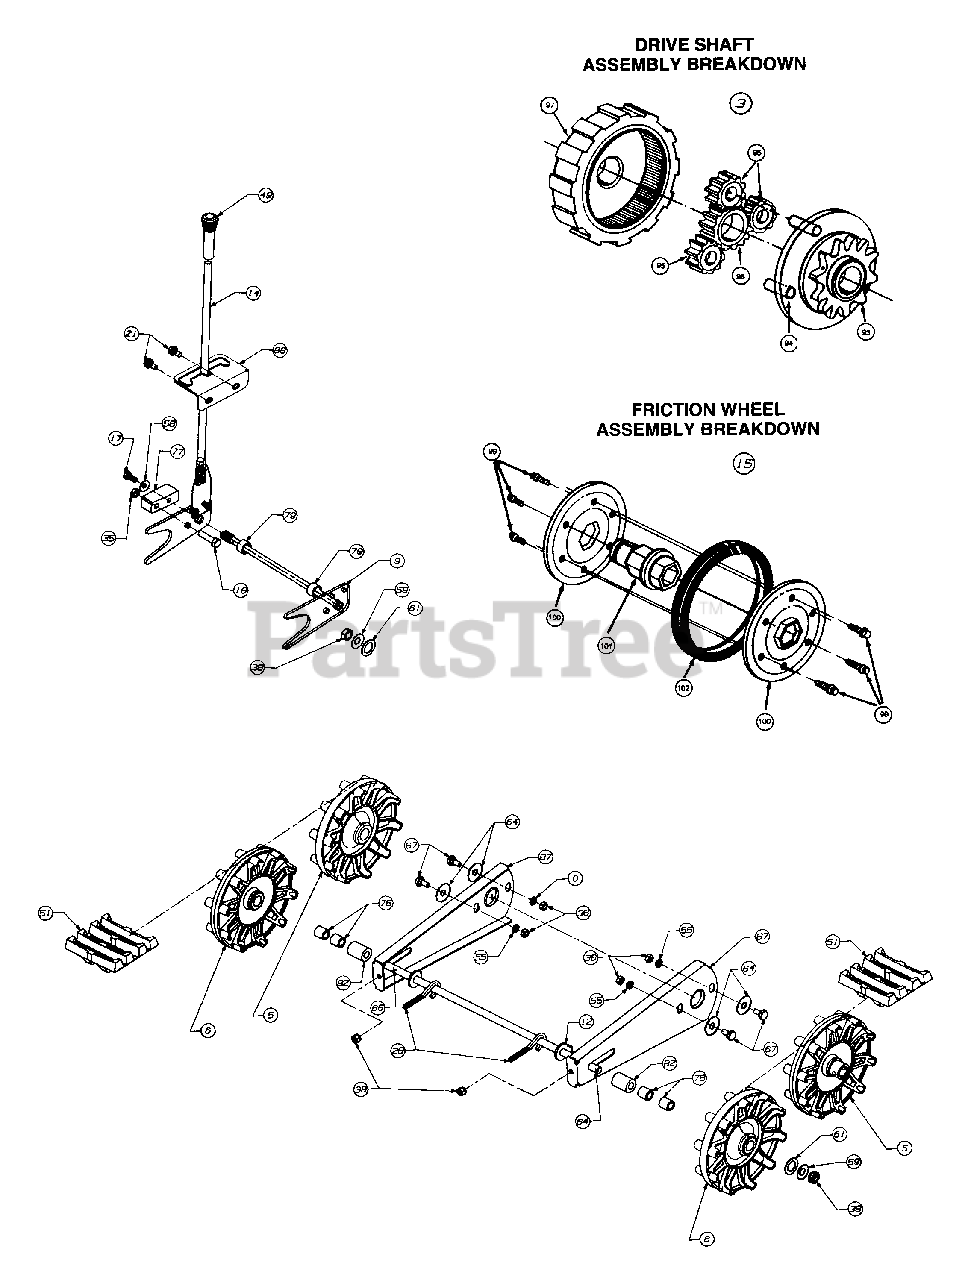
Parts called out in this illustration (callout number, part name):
3	Drive Shaft Assembly
5	Wheel Track Drive
6	Wheel Track Idler
15	Wheel Friction
17	Screw, Hex
18	Hex Screw
21	Screw, Hex
28	Bolt, Eye
35	Nut, Lock
36	Nut, Hex
38	Hex Ins. Jam
39	Hex L-Nut
51	Track
55	Washer, Lock
58	Washer, Bell
59	Washer, Bell
61	Washer, Flat
64	Washer, Flat
66	Lubricant
67	Shoulder Screw
77	Lift, Shaft Drive
78	Spacer
79	Spacer
82	Spacer
93	Carrier
94	5/16" Dowel Pin
95	12 Tooth Gear
96	18 Tooth Gear
97	Ring Gear
99	Self-Tap Screw
100	Friction Plate
101	Friction Wheel Hub
102	Friction Wheel Rubber
